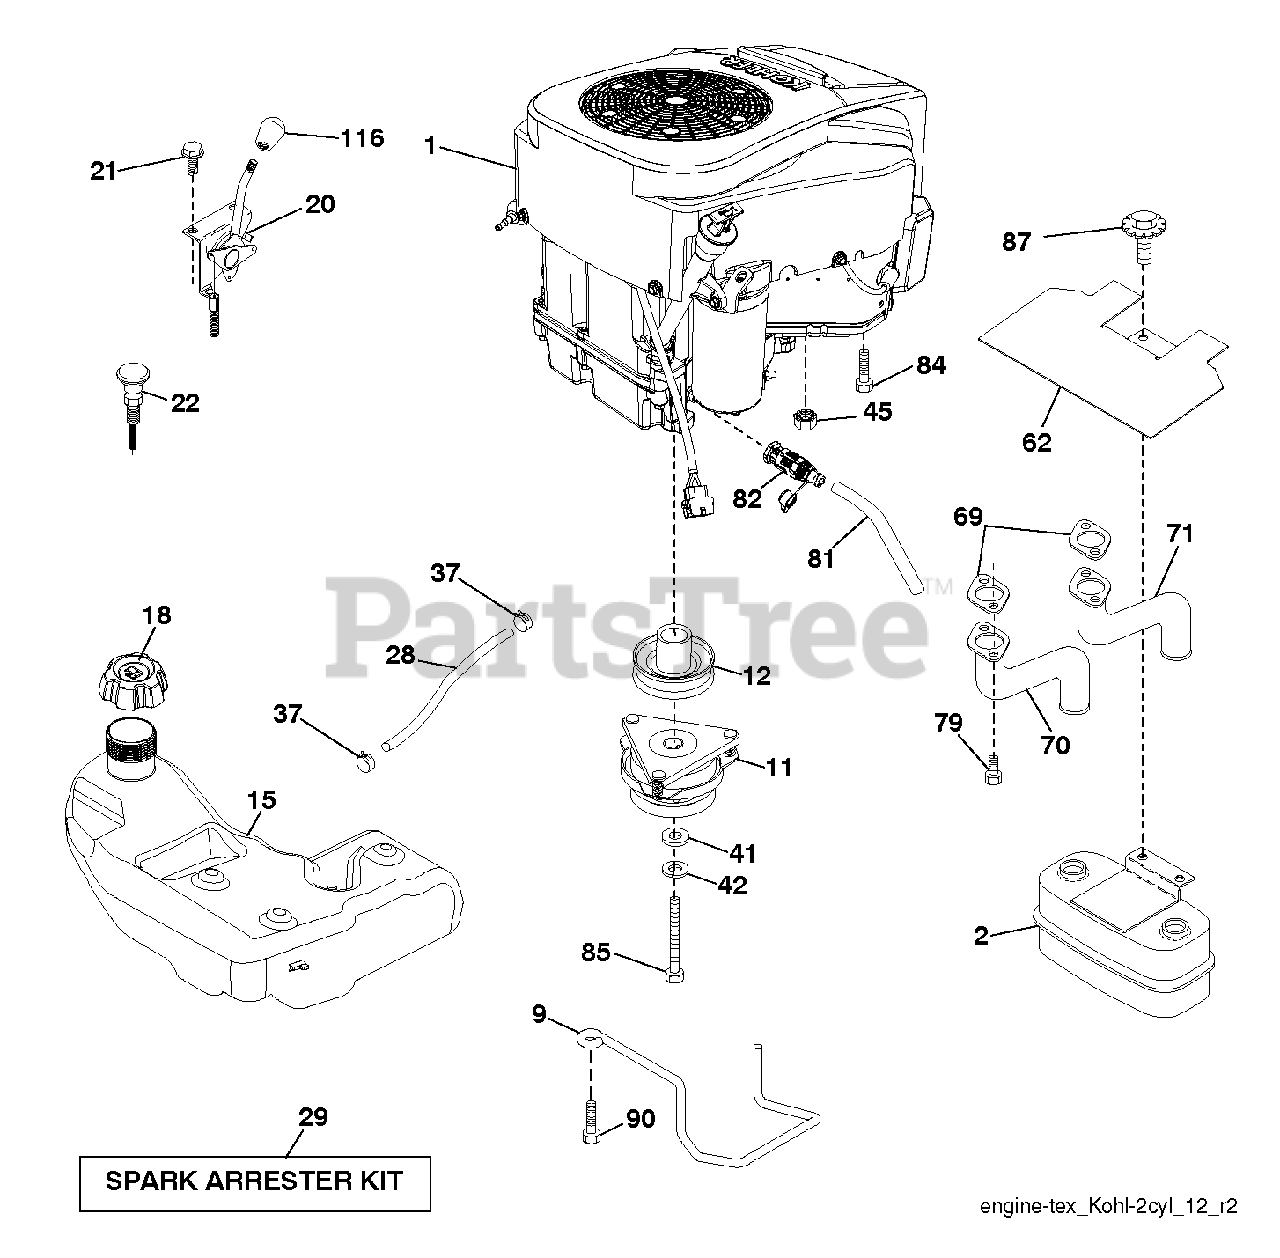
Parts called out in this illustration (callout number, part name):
2	MUFFLER.ASM.TWN.EXTNDED.DFLCTR
9	KEEPER BELT ENGINE
11	CLUTCH.ELECTRIC.LT.48"*
12	PULLEY.ENGINE.TUFFTORQ
15	TANK.ASSY.3.GAL.EPA
18	CAP.ASM.FL.RITCH.3"E10.SYM.498
20	CONTROL.THROTTLE.PRO.KOHLER
21	SCREW.#10 X 0.750.BOS
22	CONTROL.CHOKE.ERGO.PUSH-IN.BLA
28	LINE.FUEL.64"REAR.EMIS
29	KIT.SPARK ARRESTOR 794945 B&S
37	HOSE CLAMP
42	LOCKWASHER
45	NUT
62	SHIELD.HEAT.MUFFLER
69	GASKET.EXHAUST.KOHL.CV18-CV26
70	PIPE.EXHAUST.LH.CV18/20
71	PIPE.EXHAUST.RH.CV18/20
79	SCREW.SOCKET HD.5/16-1
81	TUBE, DRAIN OIL ASM.
82	VALUE.OIL.DRAIN
84	SCREW 3/8-16X1
85	BOLT HEX 7/16-20X4-1/4"
87	BOLT.5/16-18UNCX1.W/SEMS.BLK
90	SCREW 3/8-16X1
116	KNOB - SHIFT
